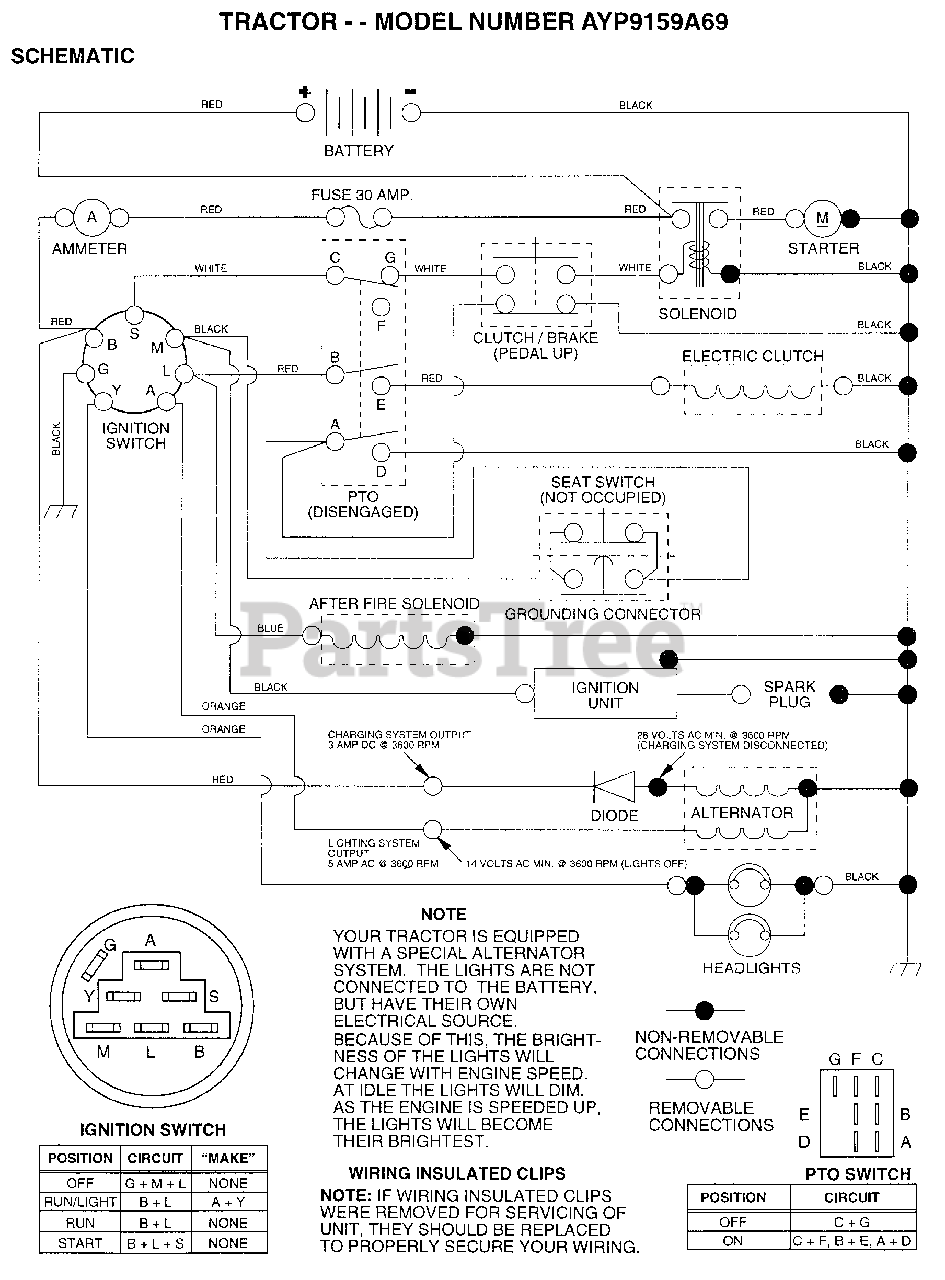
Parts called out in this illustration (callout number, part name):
2	BOLT LT
3	WASHER
4	LOCKWASHER
7	TUBE T
9	HOSE CLAMP T
15	FASTNER.SNAP-IN
20	NUT
21	"HARNESS,LIGHT SOC"
22	HEADLAMP BULB
24	"CABLE T, BATTERY"
25	CABLE.BTRY.6GA.RD
26	FUSE HYT
28	CABLE T
29	SWITCH SEAT
30	SWITCH IGN 4POS
31	NUT IGNITION
32	COVER KEY SWITCH
33	KEY
36	SCREW
38	BRACKET SWITCH IN
39	SWITCH INTERLOCKT
40	IGNITION HARNESS
41	BOLT HXHD FIN
44	NUT HXKEP 1/4X20
46	PROTECTION LOOP
70	HARNESS ENGINE
80	HARNESS.CLUT.EVX.
